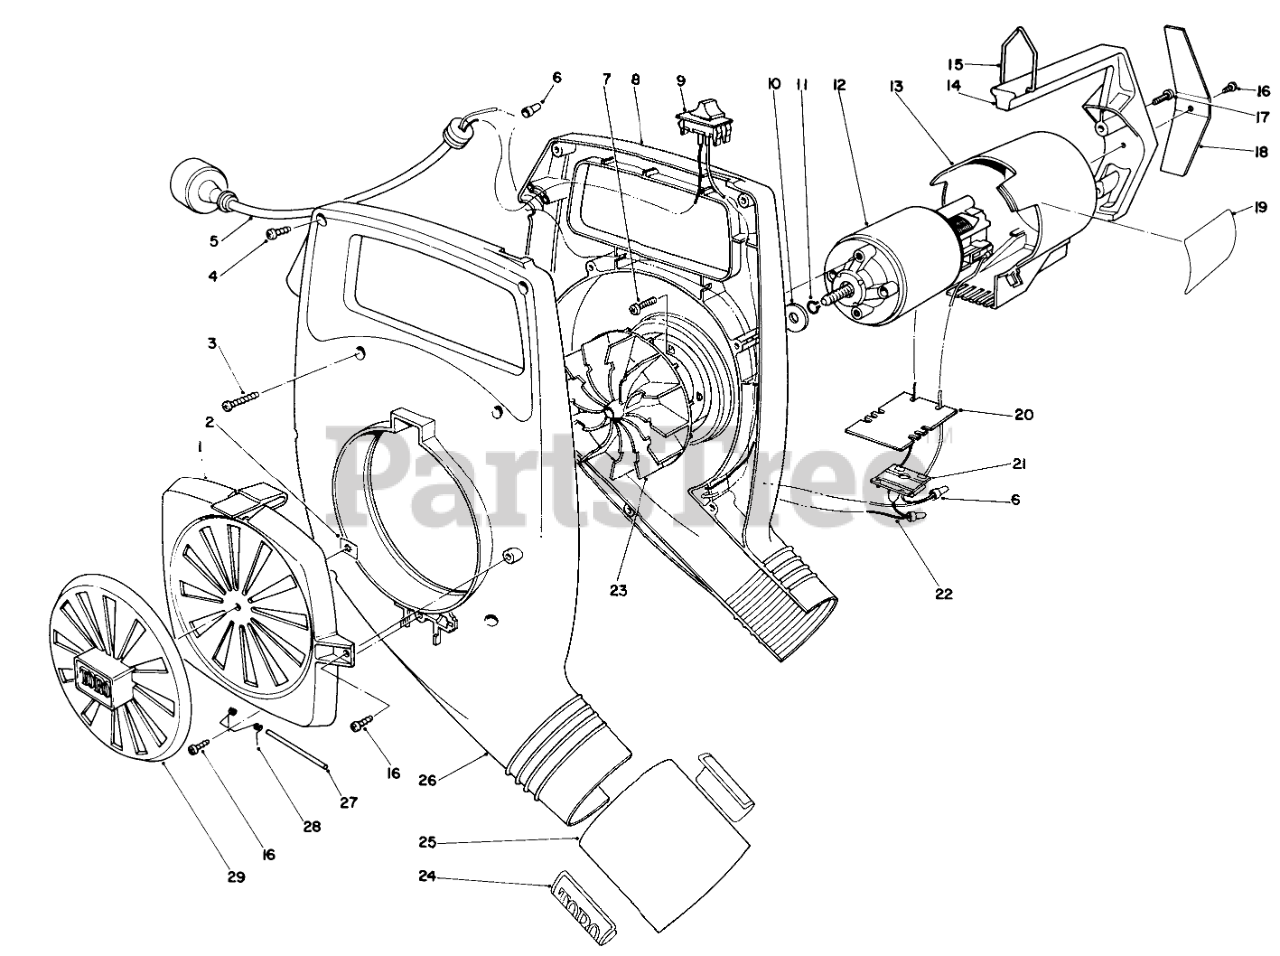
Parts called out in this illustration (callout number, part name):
1	Inlet Cover Housing (Incl. Ref. #29)
2	PUSH NUT
3	SCREW
4	Screw
5	Power Cord Assembly
6	CONNECTOR
7	SCREW
8	LH HOUSING
9	Switch (Model 51530)
10	Washer
11	Retaining Ring
12	Motor
13	Motor Cover
14	Handle
15	HANGER
16	SCREW
17	SCREW
18	WARNING PLATE
19	DECAL - 400TX
20	Mounting Board
21	P.C. Board Assembly
22	LEADWIRE ASM
23	Impeller Assembly
24	Decal-Tube Collar
25	Sleeve-Ferrule
26	Housing-Inlet Side
27	HINGE PIN
28	Spring
29	Inlet Cover
